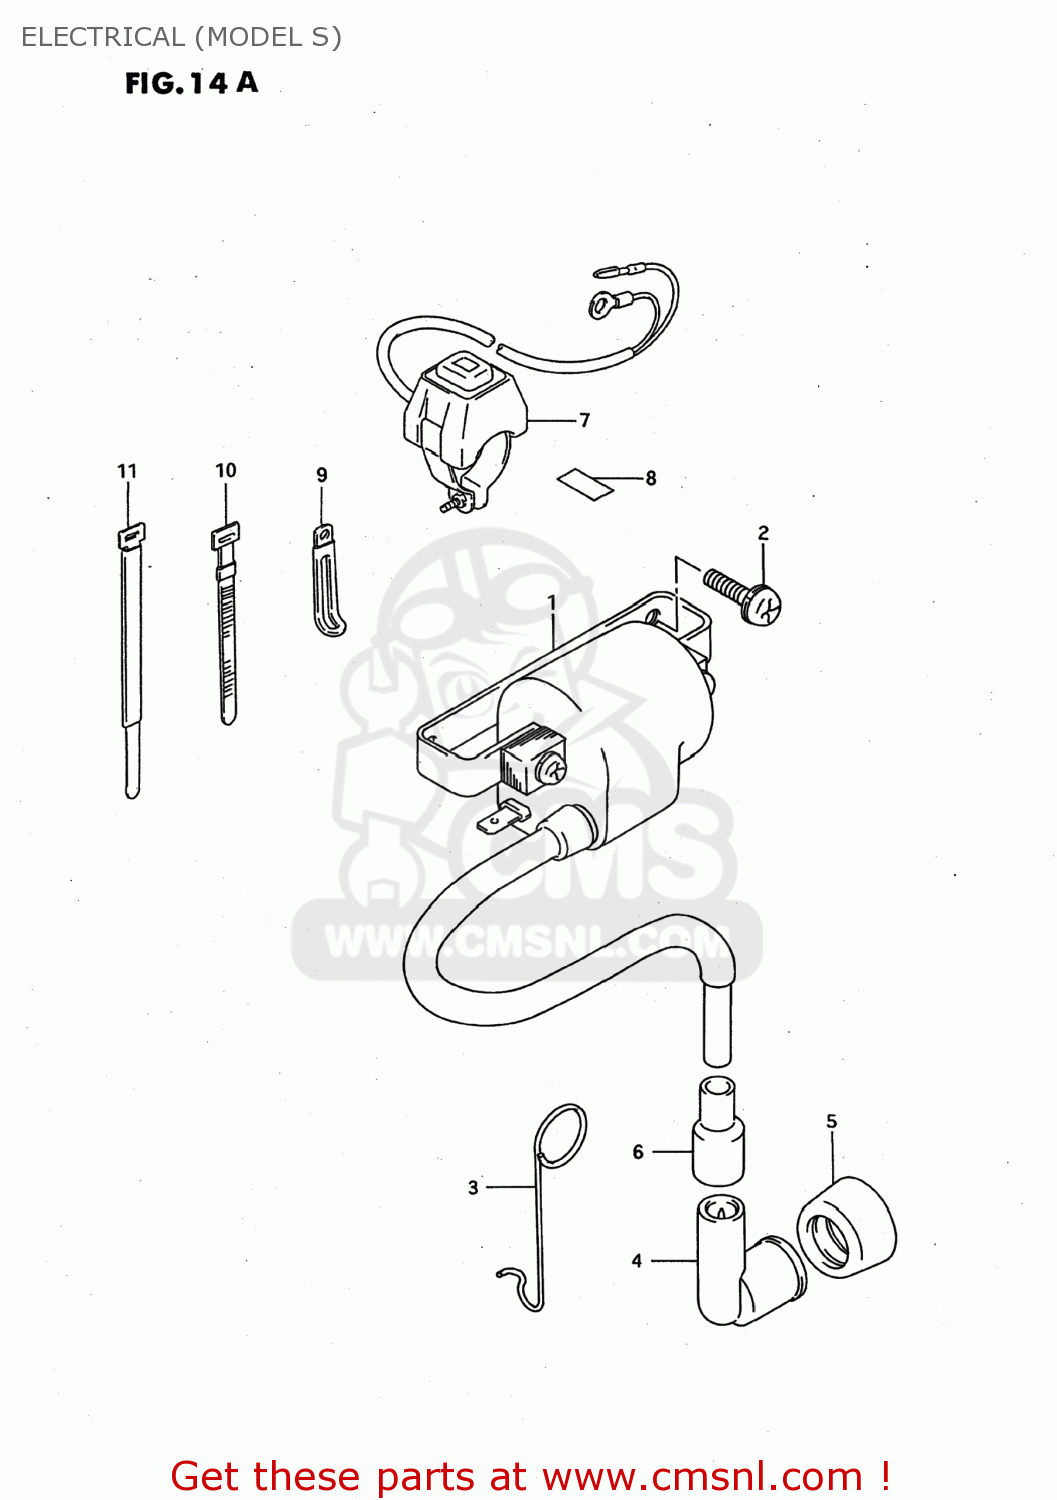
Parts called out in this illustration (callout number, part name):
1	UNIT & COIL ASSY,IGNITION
2	SCREW
3	CLIP
4	CAP ASSY,SPARK PLUG
5	SEAL,SPARK PLUG
6	SEAL,HIGH TENSION CORD
7	SWITCH ASSY,ENGINE STOP
8	LABEL (ENGINE STOP)
9	CLAMP(L:45)
10	CLAMP(L:120)
11	CLAMP
